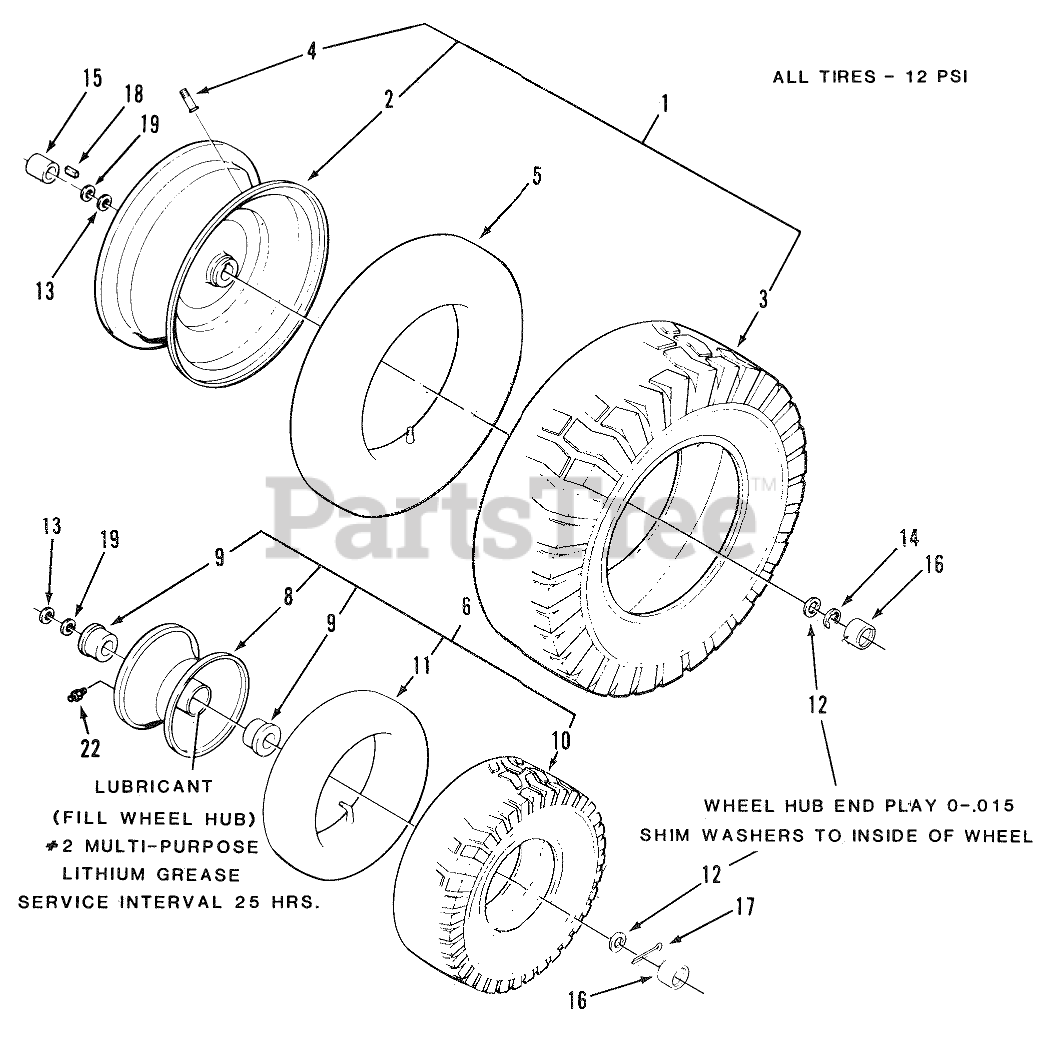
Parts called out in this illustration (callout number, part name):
1	ASSY WHEEL & TIRE
2	ASSY WHEEL
3	TIRE TURF SAVER 16X6.50-8
4	VALVE
5	TUBE-INNER
6	ASSY-WHEEL & TIRE
8	ASS'Y-WHEEL
9	BUSHING
10	Tire-Front 4-10 X 3.50-4
12	WASHER-FLAT
13	WASHER
14	E Ring
15	LH AXLE SPACER
16	HUB CAP-FLAT BLACK
17	Cotter Pin
18	SQ KEY
19	WASHER-SHIM
